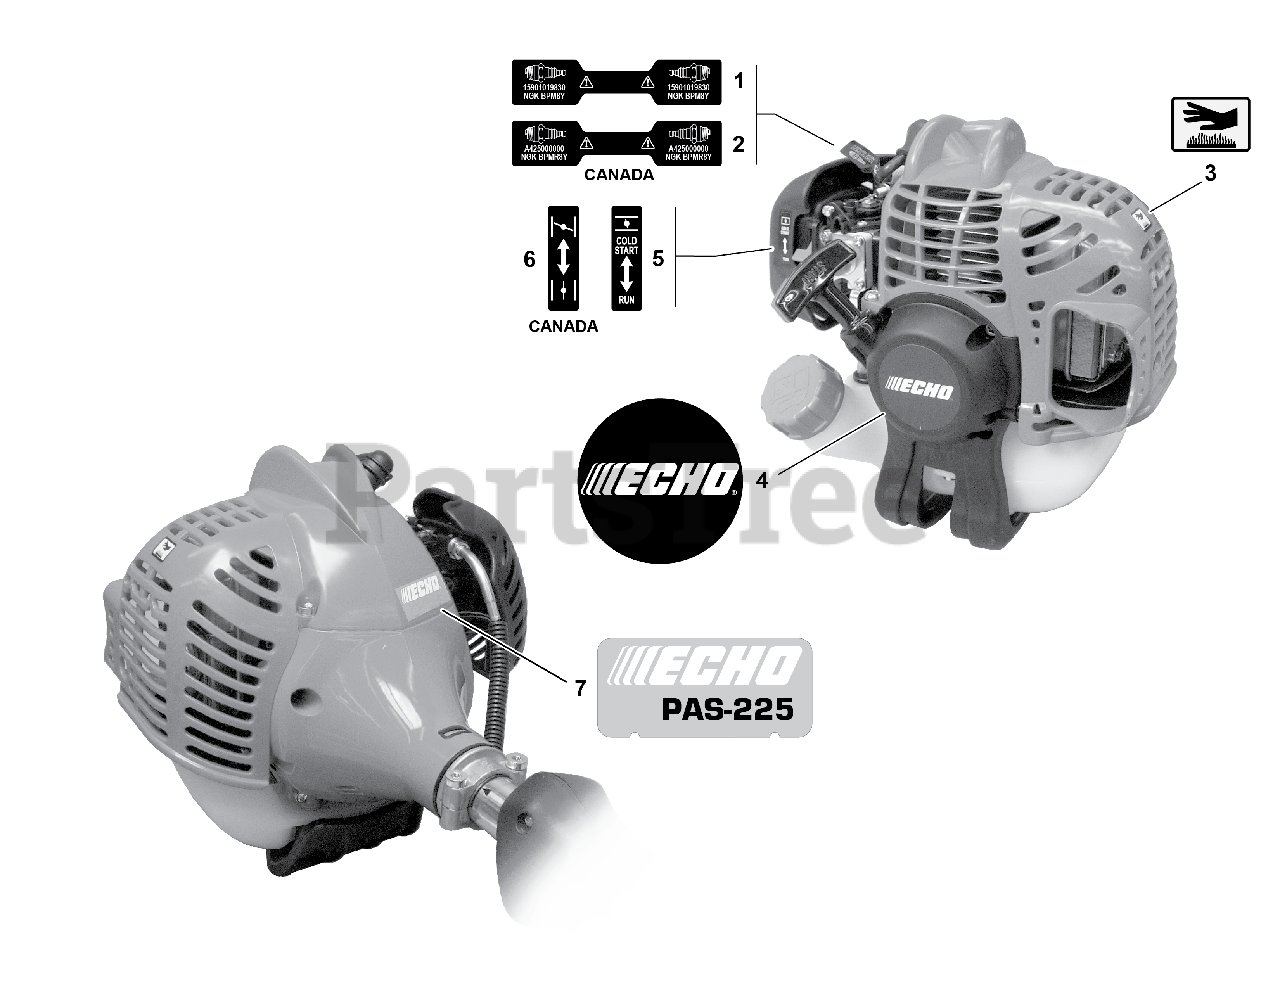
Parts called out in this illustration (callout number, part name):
1	LABEL - SPARK PLUG -- BPM-8Y
2	LABEL - SPARK PLUG -- BPMR-8Y
3	LABEL - HOT SURFACE
4	LABEL - ECHO
5	LABEL - CHOKE
6	LABEL - CHOKE
7	LABEL - MODEL -- PAS-225
